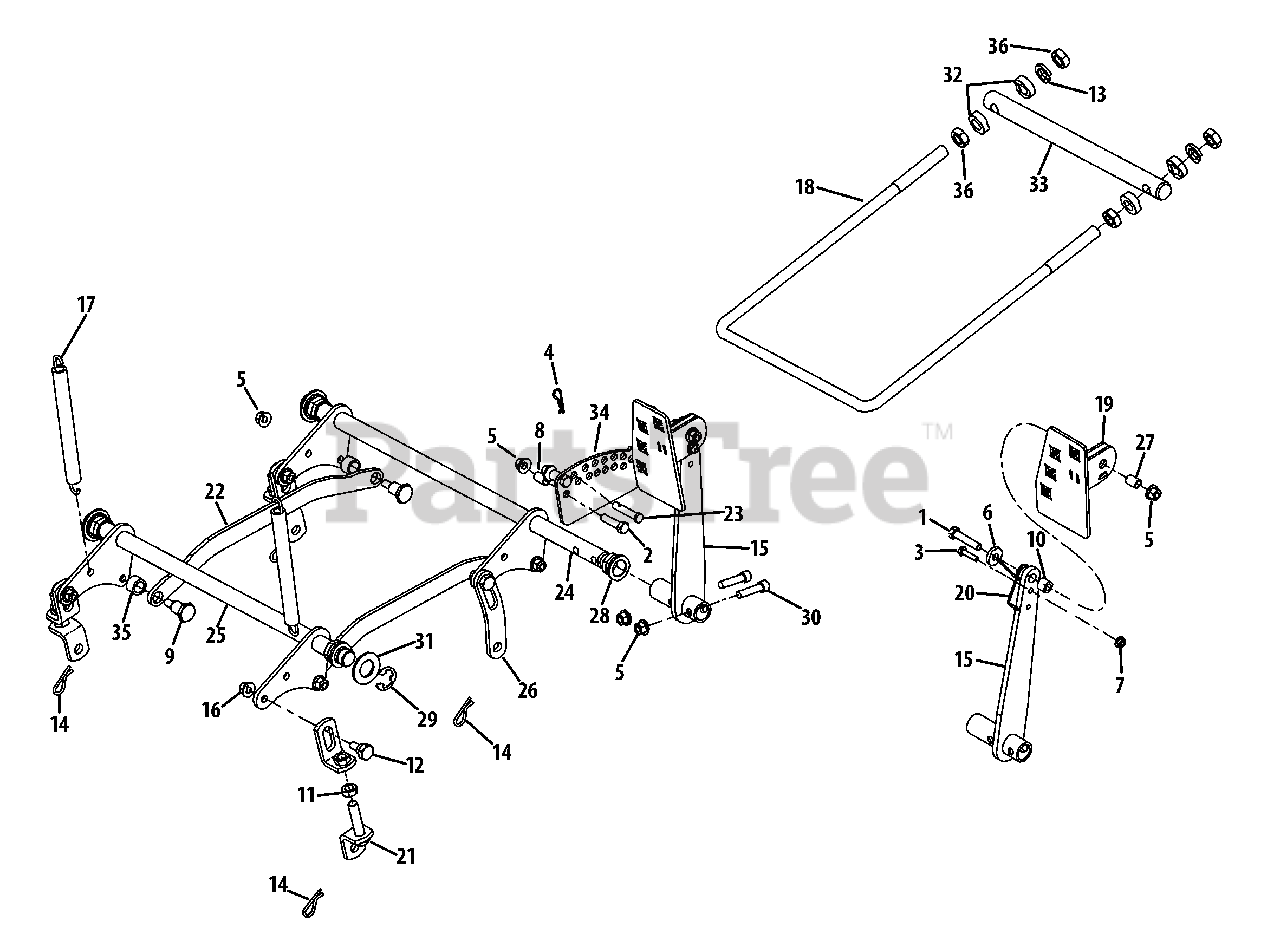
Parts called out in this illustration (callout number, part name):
1	Hex Screw, 3/8-16 x 1.75
2	Hex Screw, 3/8-16 x 1.50
3	Hex Screw, 1/4-20 x 1.00
4	Pin, Internal Cotter, .08 x 1.56
5	Counterlock Flange Nut, 3/8-16
6	Flat Washer, .385 x 1.0 x .135
7	Flange Toplock Nut, 1/4-20
8	Spacer, .375 x .500 x .750
9	Shoulder Bolt, 3/8-16 x .625 x .830
10	Spacer, .385 x .625 x .500
11	Jam Nut, 1/2-20
12	Shoulder Bolt, 3/8-16 x .56 x .27
13	Lock Washer, 5/8
14	Cotter Pin, Internal, .125 Dia.
16	Adjustable Deck Lift Bracket
17	Extension Spring, .75 x 7.89 x .14
18	Front Lift Rod
19	Foot Pedal Assembly
20	Torsion Spring, .900 x 2.3 x .09
21	Lower Bracket Assembly
22	Lift Connecting Link
23	Clevis Pin, 3/8 x 2.00
24	Front Shaft Assembly
25	Rear Shaft Assembly
26	Curved Link Plate
27	Spacer, .380 x .500 x .667
28	Hex Flange Bearing, 7/8
29	Ring, E-Type, .875
30	Sockt Cap Screw, 3/8-16 x 1.50
31	Washer, .940 x 1.75 x .105
32	Spacer, .635 x 1.2 x .41
33	Trailing Link Pivot Rod
35	Spacer, 632 x .877 x .548
36	Jam Nut, 5/8-11
